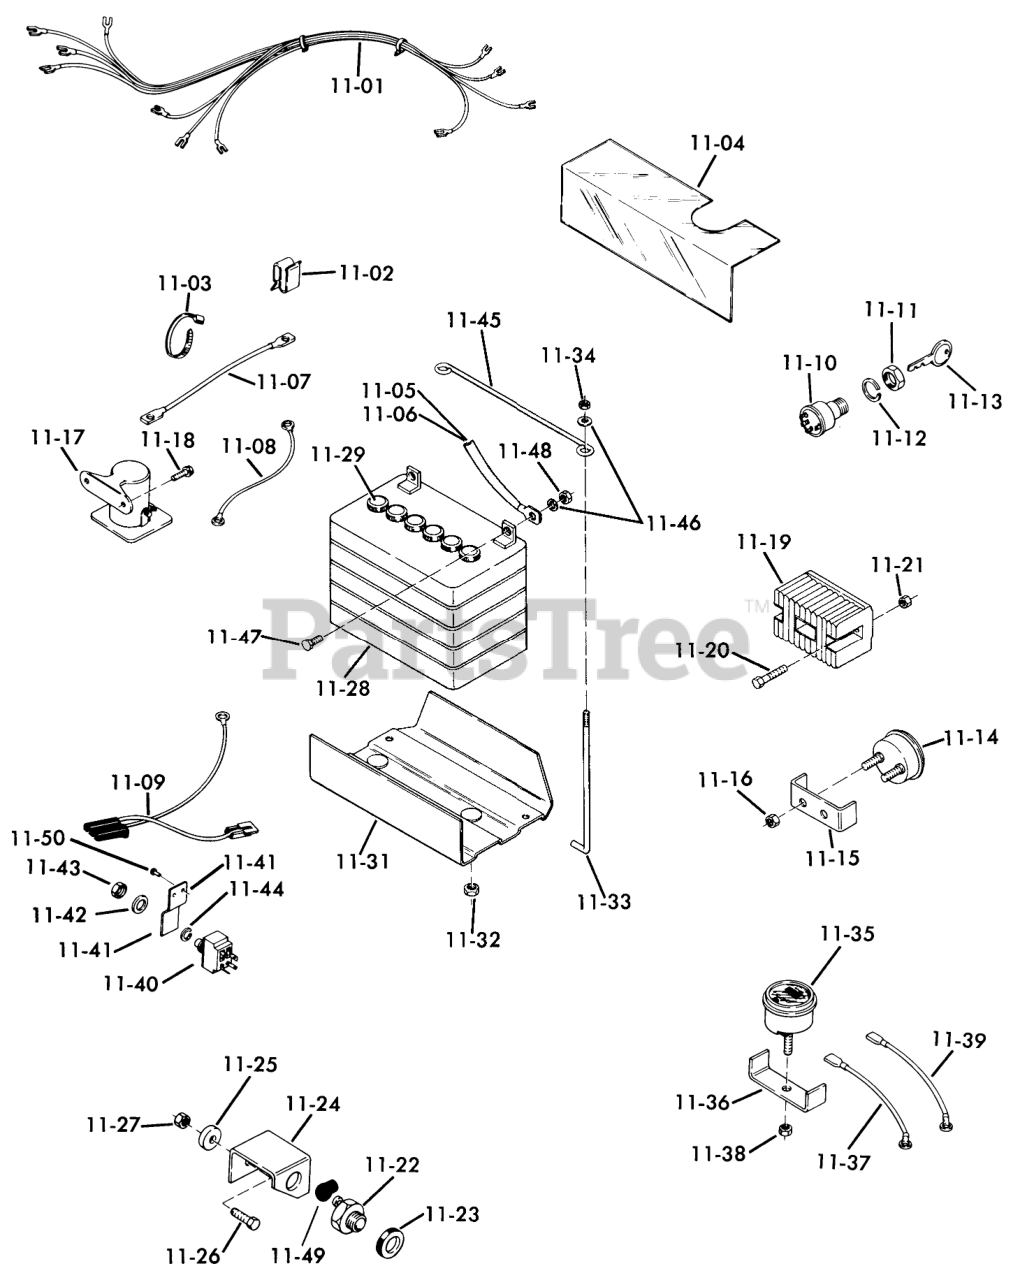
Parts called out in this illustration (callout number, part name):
11-01	WIRING HARNESS & DIA
11-02	SPEED CLIP
11-03	PLASTIC TIE
11-04	CONTROL PROTECTOR
11-05	Wire
11-06	Wire
11-07	Wire
11-09	Wire Assembly-Interlock to Harness
11-10	SWITCH-IGNITION
11-12	LOCKWASHER
11-13	Key-EL
11-14	AMMETER W/CLAMP
11-15	Clamp
11-16	HEX NUT 10-32 E.S.
11-17	Solenoid
11-18	Screw
11-19	REGULATOR-RECTIFIER
11-20	Bolt
11-21	Nut
11-22	SWITCH-INTERLOK CLUT
11-23	NUT-SPECIAL 9/16-18
11-24	Bracket
11-25	WASHER
11-26	BOLT
11-27	Nut
11-28	Battery
11-31	Battery
11-32	Nut
11-33	Hook
11-34	Nut
11-35	Hour Meter
11-36	Clamp
11-37	SY WIRE HR METER G
11-38	Nut
11-39	Wire Assy
11-40	SWITCH-CLUTCH
11-41	CLIP-SWITCH
11-42	WASHER
11-43	NUT-HEX
11-44	TAB-WASHER
11-45	ROD-HOLD DOWN
11-47	Bolt
11-48	Nut
11-49	Terminal Cover
11-50	RIVET
